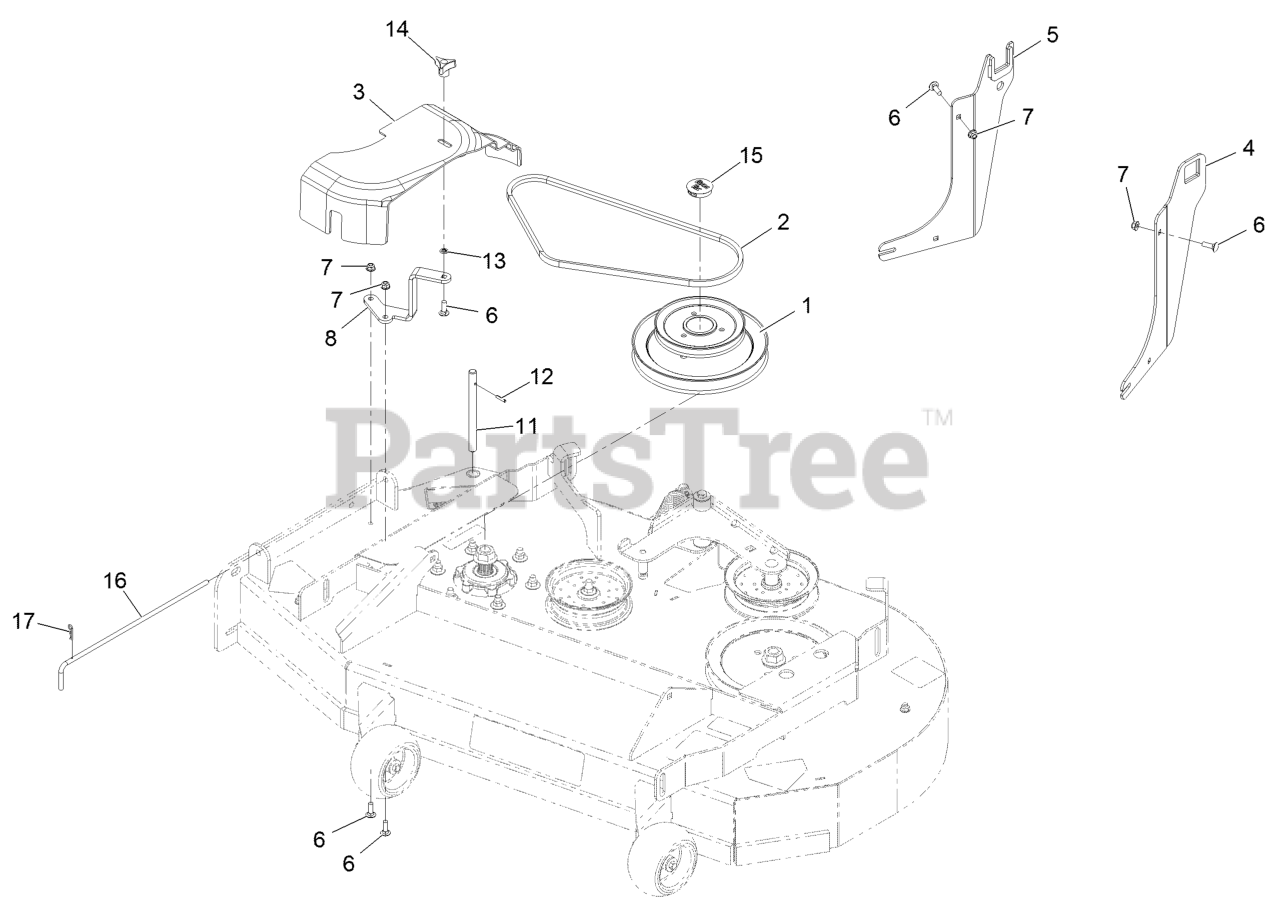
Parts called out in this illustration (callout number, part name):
1	JACKSHAFT-UV DRIVE, 44 SP
2	BELT, BLOWER DRIVE 72
3	COVER-BELT, UV 44
4	BRACKET ASM, LH
5	BRACKET ASM, RH
6	BOLT-CARR
7	NUT-HF, NI
8	BRACKET-BELT COVER 44
11	SHAFT-CATCHER, GRASS
12	PIN-ROLL
13	RING-RETAINING, BOLT
14	KNOB-3 PRONG
15	PLUG, BLACK NYLON 1.75
16	PIN,CHUTE PIVOT
17	PIN-COTTER
